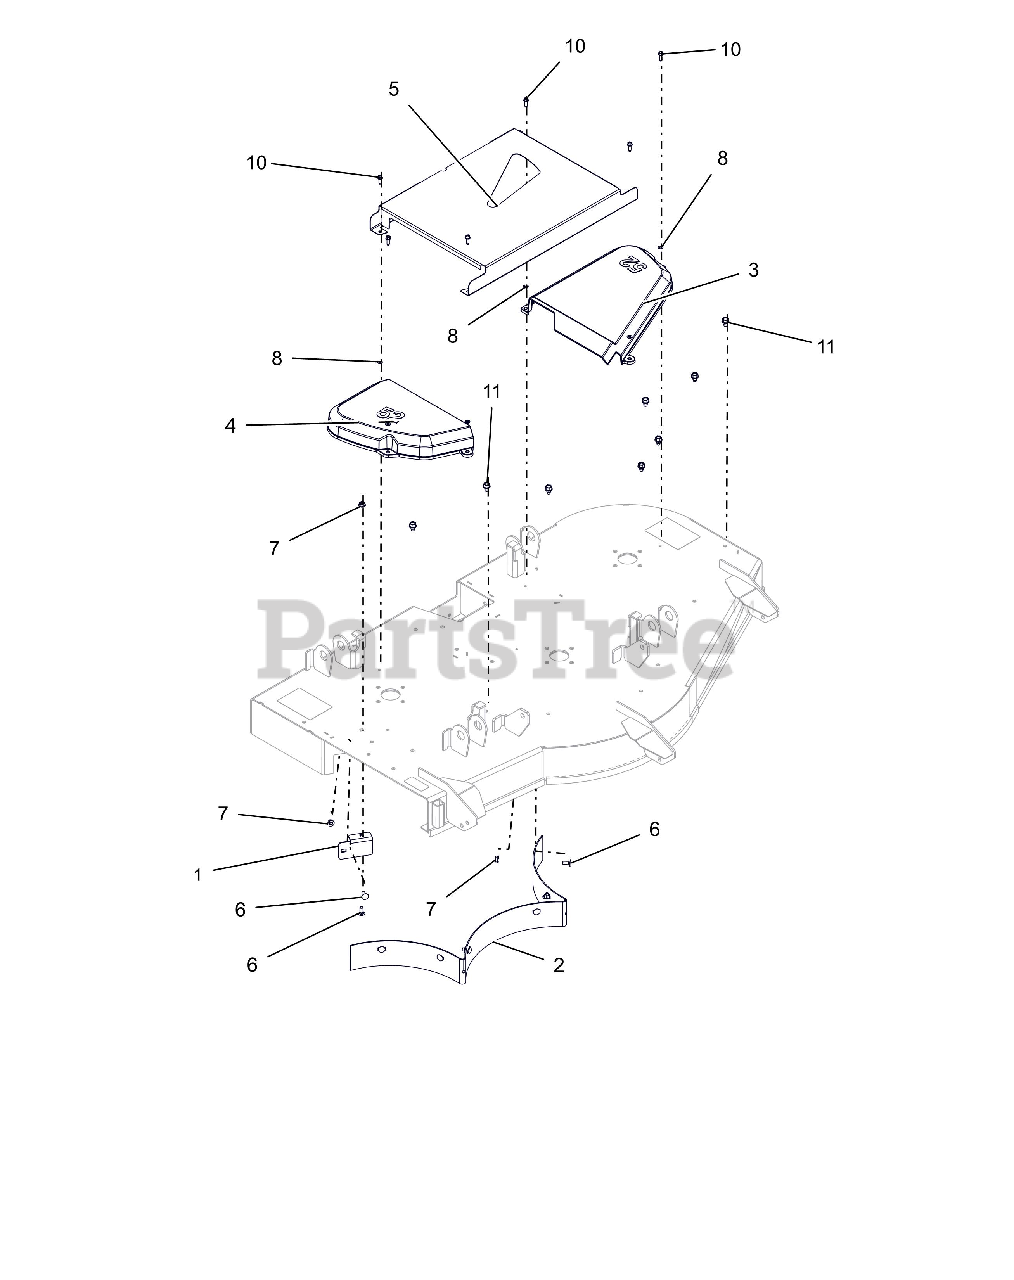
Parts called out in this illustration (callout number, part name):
1	STRIP, DEFLECTOR - 52"
2	BAFFLE, REAR - REMOVABLE 52"
3	COVER, BELT 52" LH
4	COVER, BELT 52" RIGHT
5	GUARD, IKON BELT - 52" CE
6	@BLT-RDHDSQNK .31-18X.75 G5YZ
7	@NUT-LK-TOP-FLG .31-18 YWZC
8	NUT-PUSH .25X.50 O.D.
10	SCR-TAP-PM .25-20X.75 TR YWZ
11	@SCR-TAP .38-16X.50 HWH TR YWZ
